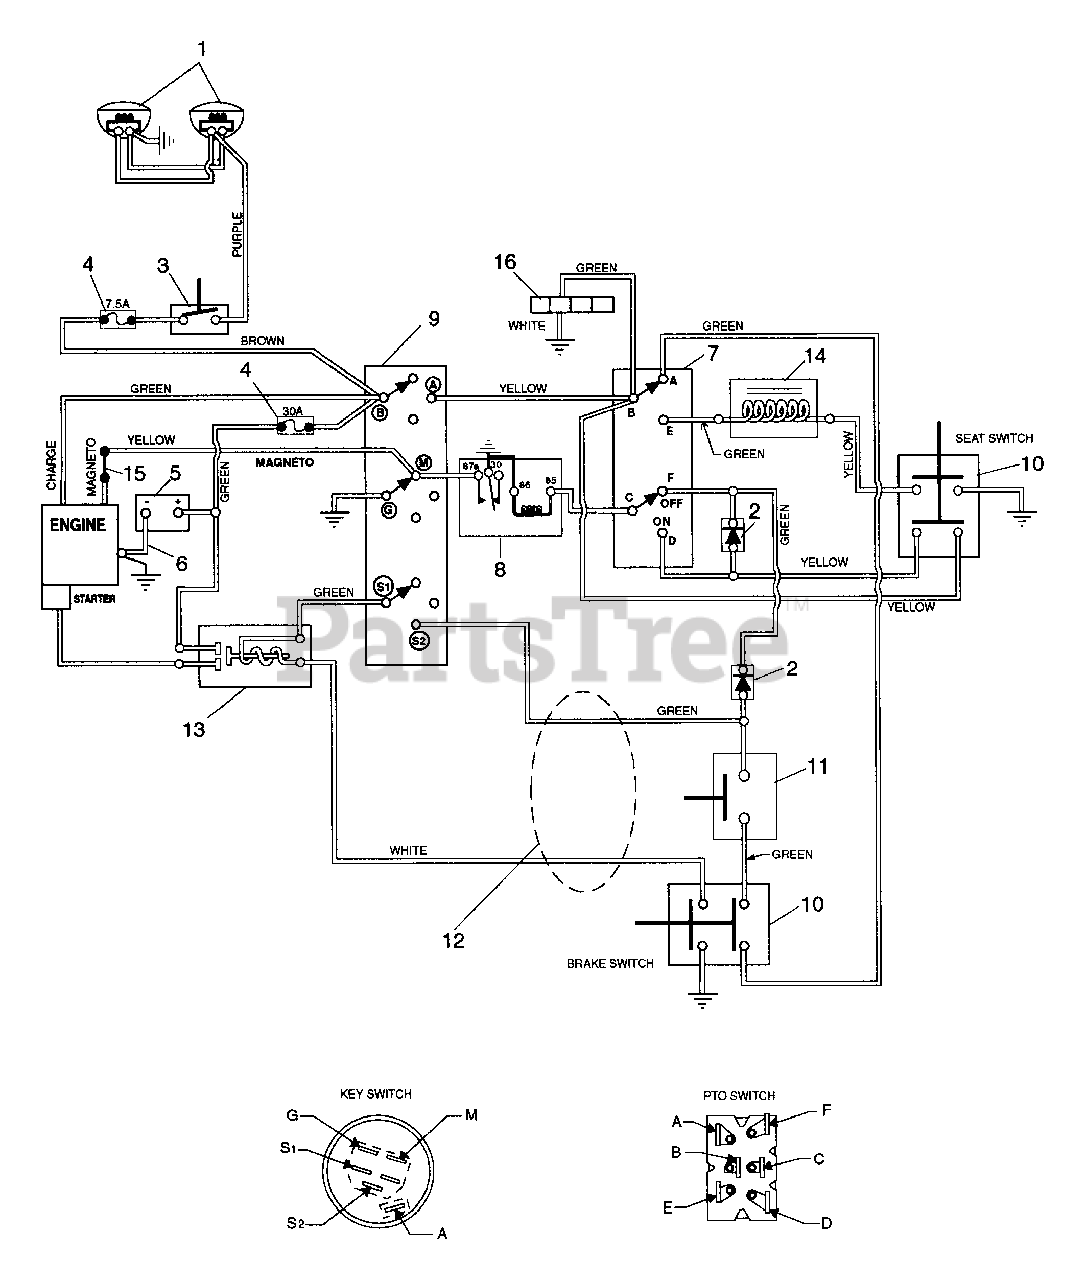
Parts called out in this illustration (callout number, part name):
1	HEADLIGHT- L.H.
1	HEADLIGHT- R.H.
2	DIODE & HOUSING
3	LIGHT SWITCH
4	7.5 AMP FUSE
4	30 AMP FUSE
5	BATTERY
6	GROUND CABLE .31X22.00X.31
7	SWITCH ASSEMBLY- PTO
8	RELAY
9	KEY SWITCH
10	SWITCH- DOUBLE POLE N.O./N.O.
11	SWITCH-NEUTRAL START N.O.
12	WIRE HARNESS- YT15G
13	SOLENOID
14	ELECTRIC CLUTCH/BRAKE(1.8AMP)
15	WIRE HARNESS ADAPTER
16	HOUR METER W/ LEADS
